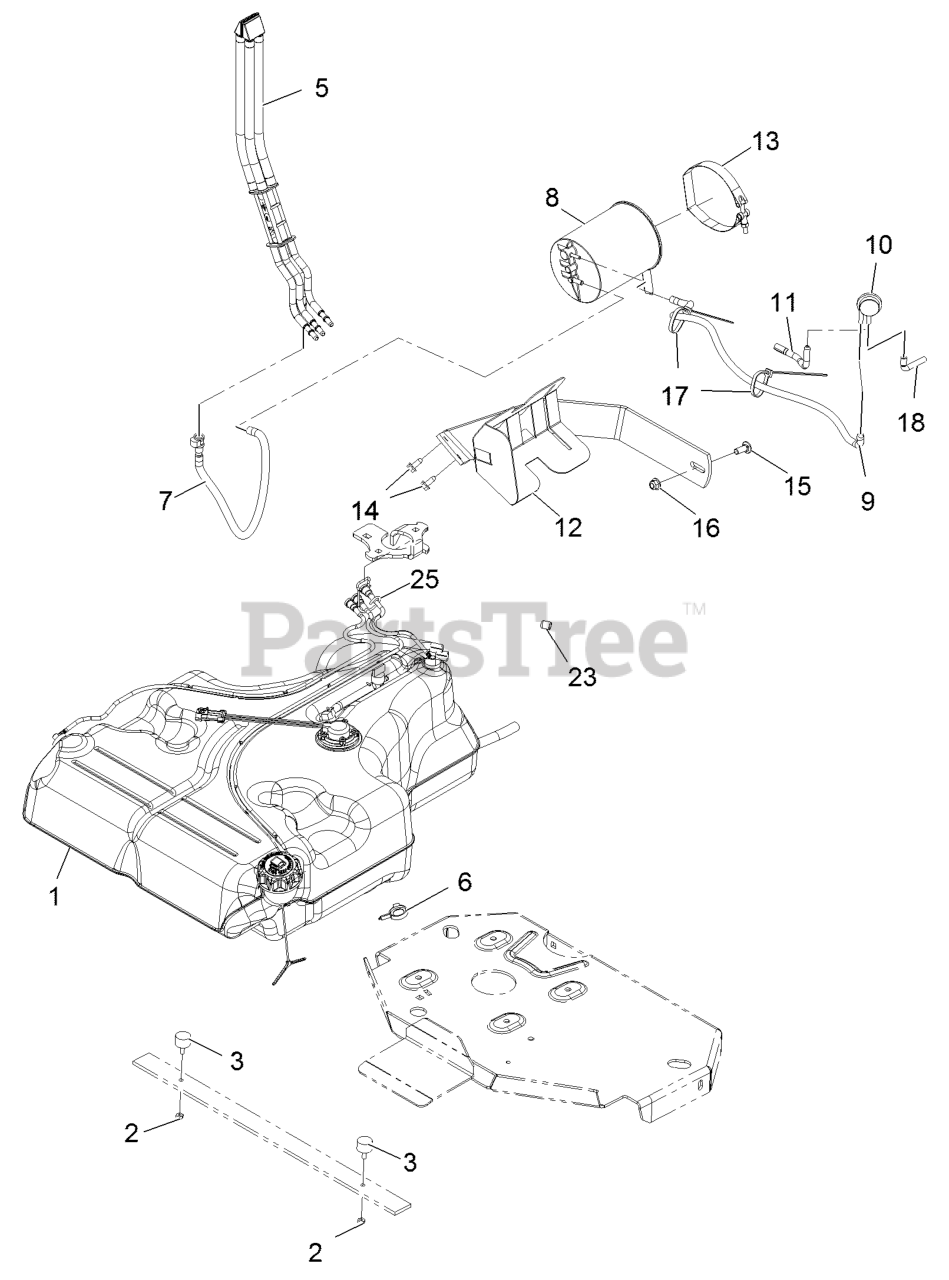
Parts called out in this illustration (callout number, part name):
2	NUT-JAM
5	FUEL MANIFOLD VENT ASM
6	CLAMP-HOSE
7	VENT HOSE ASM
8	CANISTER-CARBON, 1200CC
9	HOSE-VENT, FORMED
10	VALVE-CONTROL, VACUUM
11	HOSE-VENT, FORMED
12	MOUNT-CANISTER
13	CLAMP, T-BOLT
14	Screw-HWH 5/16-18 X 3/4 Tf
15	SCREW-CARR
16	NUT-HF, NI
17	TIE-PLASTIC
18	HOSE-VENT, FORMED
23	PLUG-PORT
25	RETAINER-LINE, VAPOR
